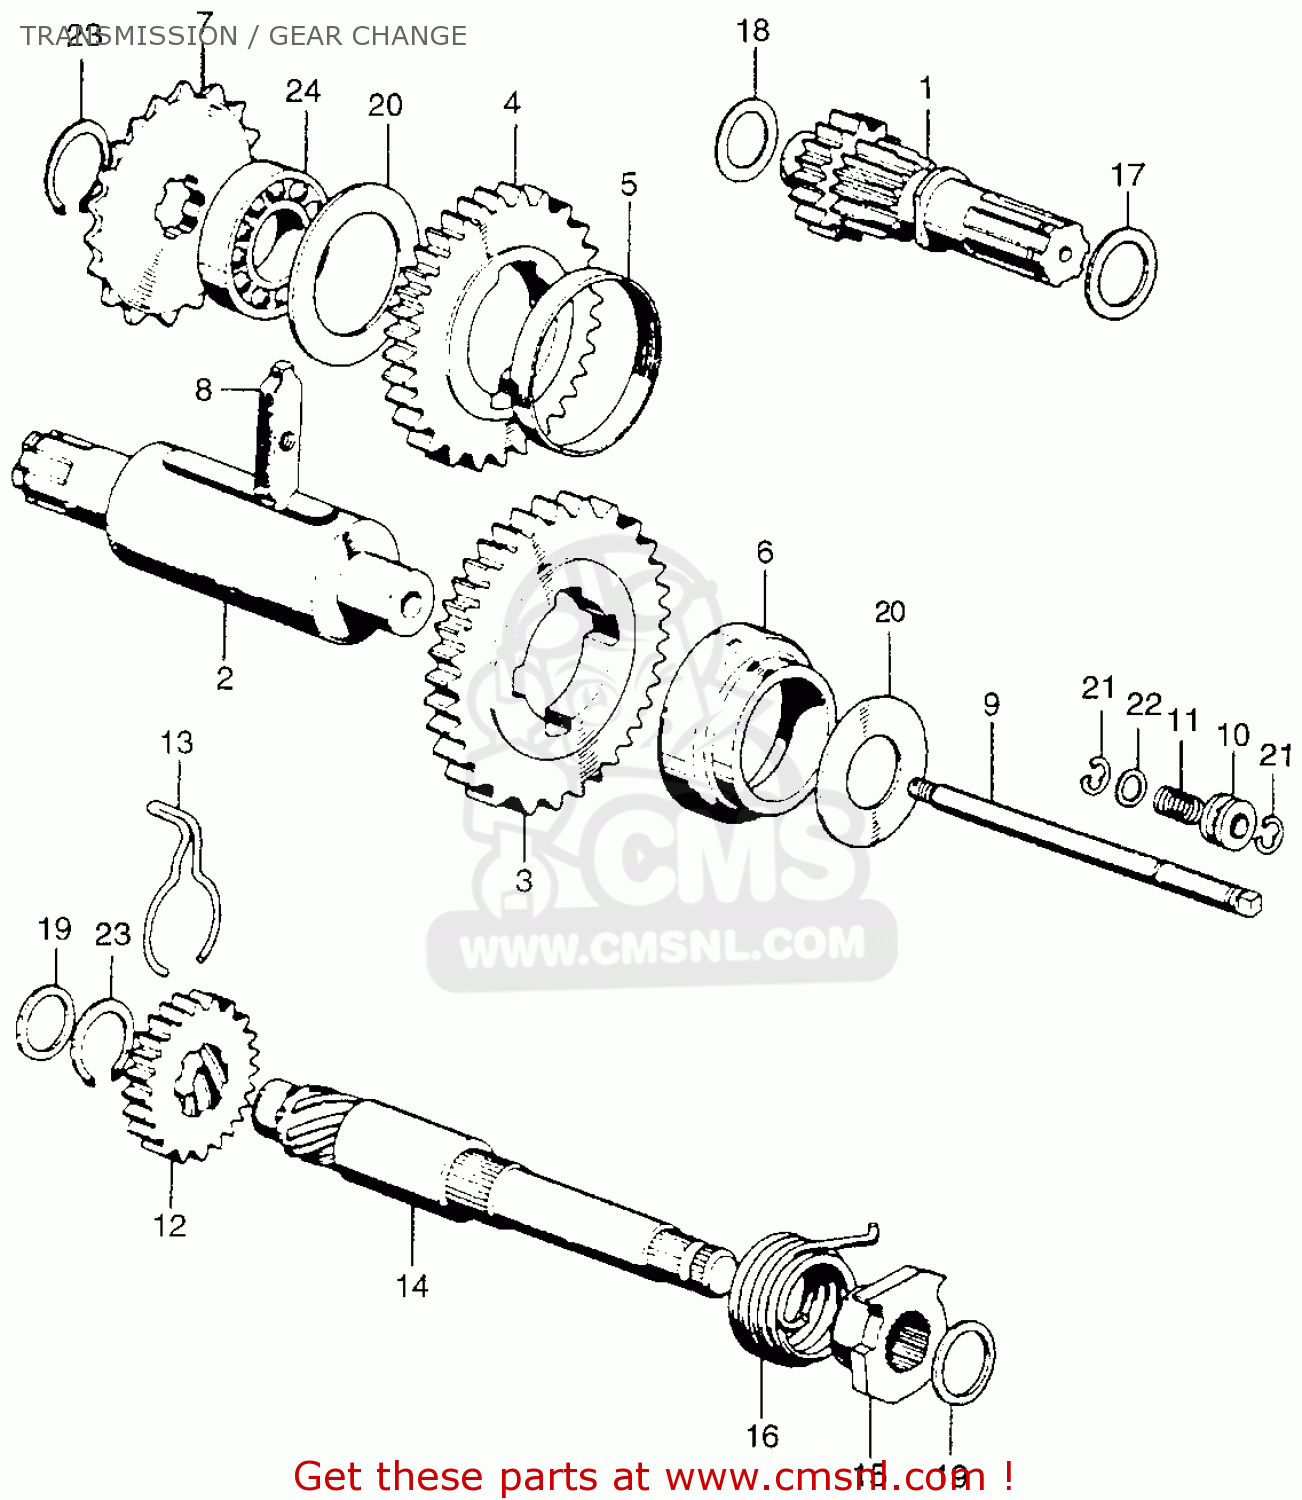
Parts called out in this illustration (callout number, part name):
1	MAINSHAFT, TRANS
2	COUNTERSHAFT, TRANS
3	LOW GEAR,COUNTER
4	GEAR (42T)
5	COLLAR,50MM
6	SPACER, SHAFT
7	SPROCKET,DRIVE
8	PAWL,GEAR.CHANGE
9	SHAFT,GEAR.CHANGE
10	FLANGE, PAWL SHAFT
11	SPRING
12	PINION, KICK STARTER
13	SPRING, FRICTION
14	SPINDLE,STARTER
15	RETAINER,SPRING
16	SPRING,STARTER
17	WASHER,A,THRUST
18	WASHER, THRUST
19	WASHER,THRUST30MM
20	WASHER 17MM
21	CIRCLIP,TYPE.6MM
22	WASHER PLAIN 6MM
23	CIR CLIP,EX.20
24	B/BRG RAD N/COM
